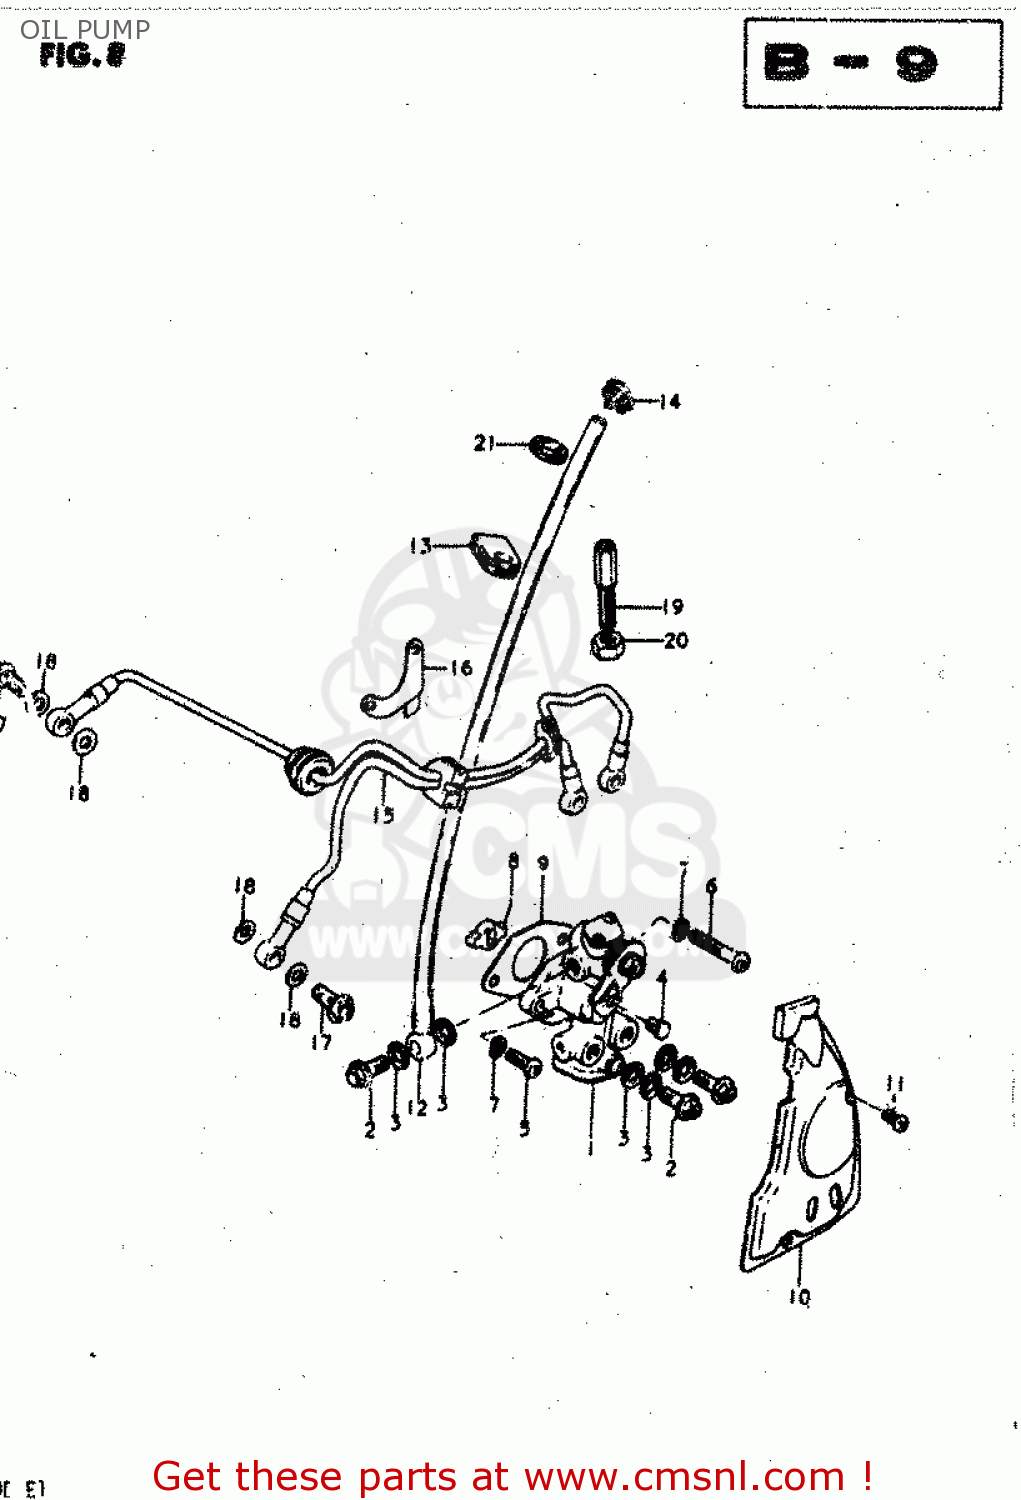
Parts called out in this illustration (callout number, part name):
1	PUMP ASSY,OIL
2	UNION BOLT
3	GASKET(6.2X11X1).2 (NAS)
4	TERMINAL,CABLE
5	SCREW
6	SCREW(5X27)
7	LOCK WASHER
8	PIECE,OIL PUMP DRIVE
9	GASKET,OIL PUMP (NAS)
10	CAP, INSPECTION
11	SCREW
12	HOSE,OIL NO.1
13	GROMMET
14	CLAMP
15	HOSE,OUTLET
16	CLAMP
17	UNION BOLT
18	GASKET(6.2X11X1).2 (NAS)
19	BOLT
20	NUT
21	GROMMET
